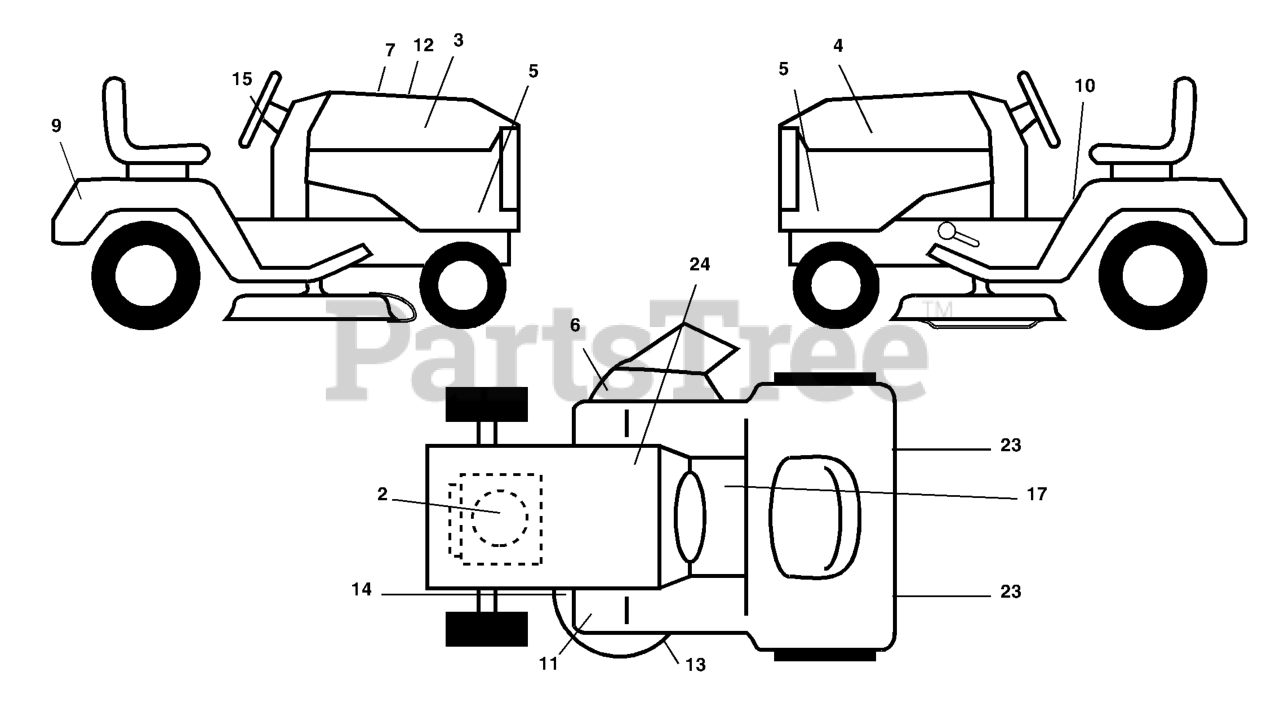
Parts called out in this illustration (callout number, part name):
2	DECAL.ENG.25HP.KAWA.HSQV.XP
3	RH HOOD DECAL
4	LH HOOD DECAL
5	DECAL HOOD SIDES
6	DECAL.WARN.KEEP.HAND.AWAY
7	AUGER HOUSING
9	DECAL, FENDER
10	DECAL FENDER DANGER
11	DECAL, FOOTREST
12	DECAL, FINAL
13	DECAL V-BELT SCHEMATIC
14	DECAL CLUTCH/BRAKE
15	DECAL.WHEEL.STEERING.HUSQ.PERM
17	DECAL, SADDLE BRAKE PARKING
23	REFLECTOR-TAIL YT
24	DECAL BTRY SYMBOLS
24	DECAL.BYPASS.FENDER.CRD.LT.YT
24	DECAL HANDLE LIFT
